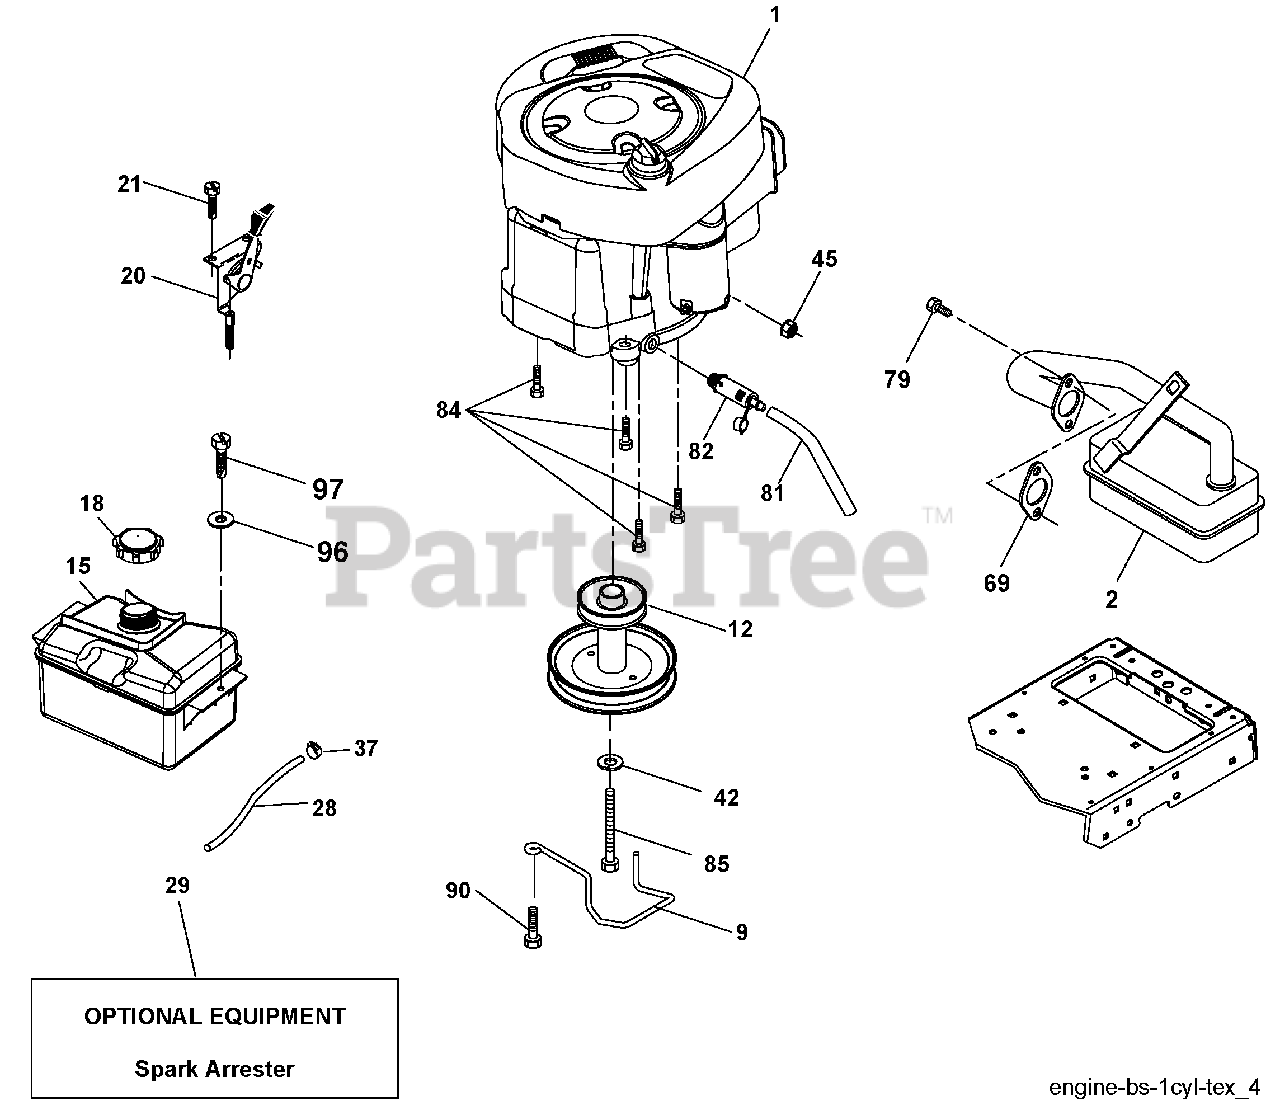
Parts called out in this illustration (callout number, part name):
2	Muffler
9	Keeper Belt Engine
12	Pulley Engine
15	Tank Fuel 1.50
18	Cap Asm
20	Control Throttle/Choke
21	Screw #10 x 0.750
28	Fuel Line
29	Spark Arrester Kit
37	Clamp Hose
42	Washer Lock 7/16
45	Nut Keps Hex 1/4-20 unc
69	Gasket
79	Screw Socket Hd 5/16-18 x .75
81	Tube Drain Oil Easy
82	Plug Drain Oil
84	Screw 3/8-16 x 1-1/4
85	Bolt Hex 7/16-20 x 4 x Gr. 5-1.5
90	Screw 3/8-16 x 1.0
96	Washer 9/32 x 7/8 x 16 Ga.
97	Screw 1/4-20 x 3/4
